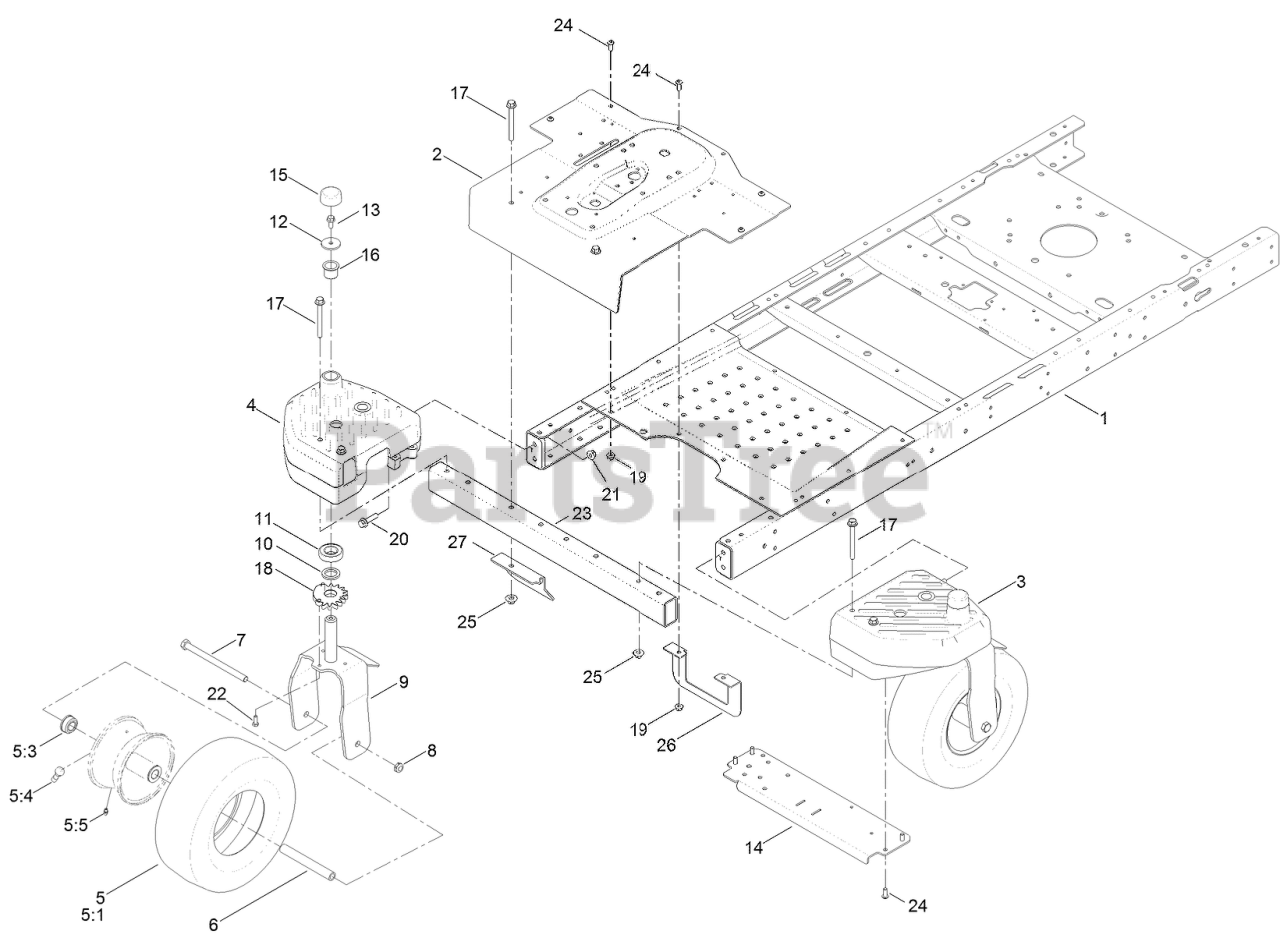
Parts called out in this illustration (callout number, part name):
1	FRAME ASM (WIDE)
2	PAN-STEER, FRONT (WIDE)
3	HOUSING-SPINDLE, LH
4	HOUSING-SPINDLE, RH
5	13 INCH WHEEL AND TIRE ASM
5:1	TIRE-13 Inch
5:3	BUSHING-FLANGE
5:4	STEM-VALVE
5:5	FITTING-GREASE
6	SPANNER
7	SCREW-HH
8	NUT-LOCK, NI
9	CASTER FORK ASM
10	WASHER-THRUST
11	BEARING-BALL
12	WASHER-FLAT
13	SCREW-HHF
14	PLATE-BRIDGE, WIDE
15	CAP-CASTER
16	BUSHING-PIVOT
17	SCREW-HHF
18	GEAR-WHEEL, 15 TEETH
19	NUT-HF, NI
20	SCREW-HHF
21	NUT-HF, NI
22	SCREW-HH
23	TUBE-FRONT, WIDE
24	SCREW-HSBH
25	NUT-FLANGE, NI
26	BRACKET-UPSTOP
27	GUARD-FRONT
